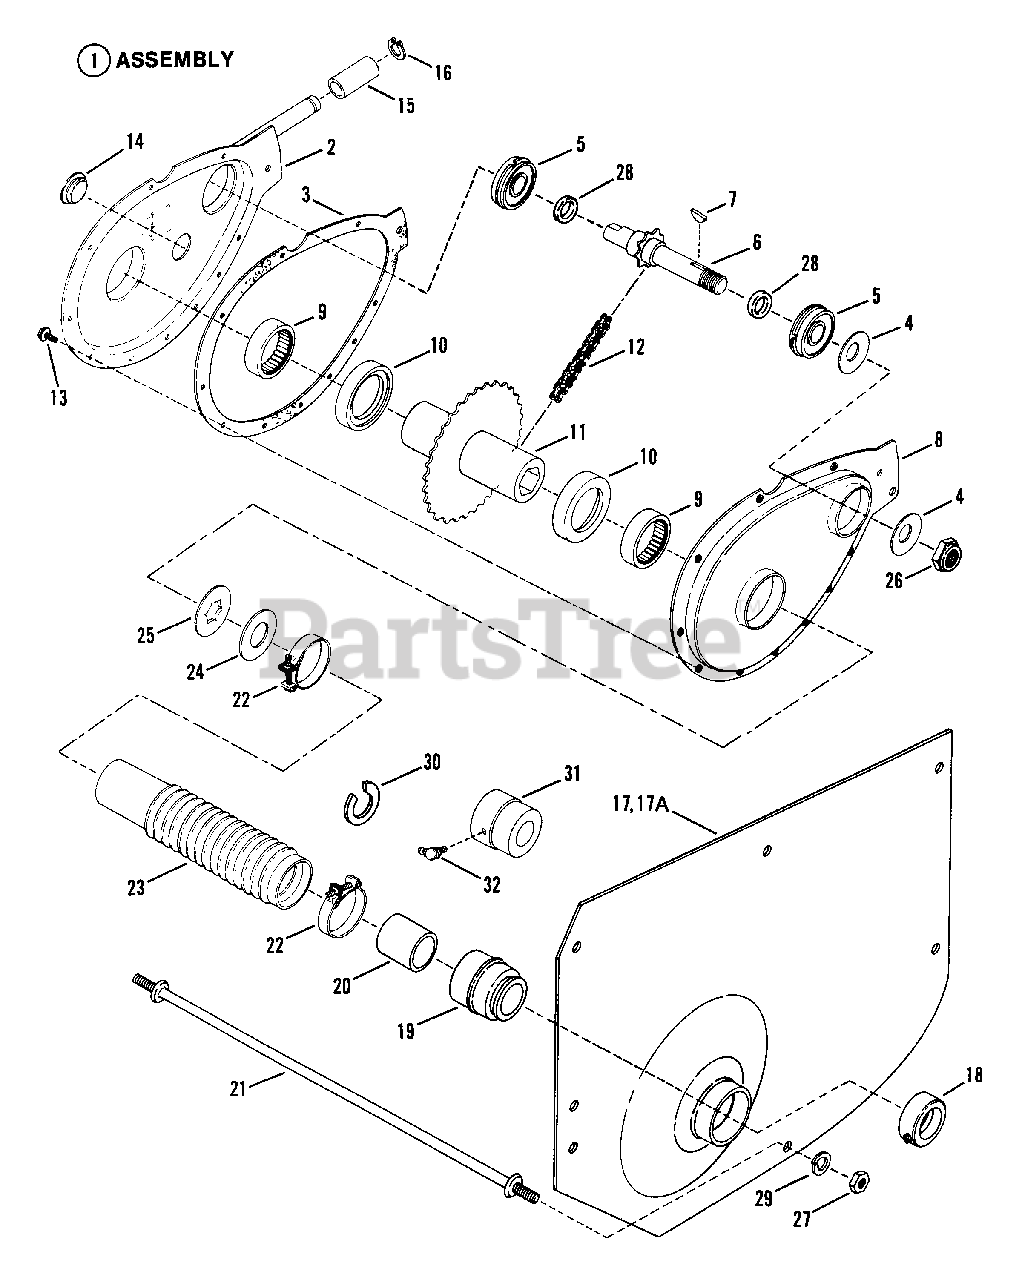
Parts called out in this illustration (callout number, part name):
1	ASSEMBLY, Chain Case
2	CASE, Sprocket
3	GASKET, Case-Cover
4	WASHER, .640 I.D. Belleville
5	BEARING, Ball
6	SPROCKET & SHAFT
7	KEY, Woodruff
8	COVER, Chain Case
9	BEARING, Needle
10	WASHER, Nylon Thrust
11	HUB & SPROCKET
12	CHAIN
13	SCREW, #10-24 x 1/2" Hex Washer Self-Tap (Torx)
14	PLUG, Oil Fill & Check
15	ROLLER
16	RING, Retaining
17	FENDER, Left Hand (1.744" I.D. Hole)
17A	FENDER, Left Hand (1.628" I.D. Hole)
18	COLLAR, Lock
19	BEARING, Left Hand Fender
20	SPACER, Left Hand
21	ROD, Cross-Tie
22	CLAMP, Boot
23	BOOT, Oil Seal
24	WASHER, Thrust Nylon
25	WASHER, Thrust
26	NUT, 5/8 - 18 Hex, E.E.S.
27	NUT, 5/16-24 Hex
28	"O" - RING
29	WASHER, 5/16 Split Lock
30	WASHER, Shim
31	BEARING, Left Hand Fender
32	FITTING, Lube
